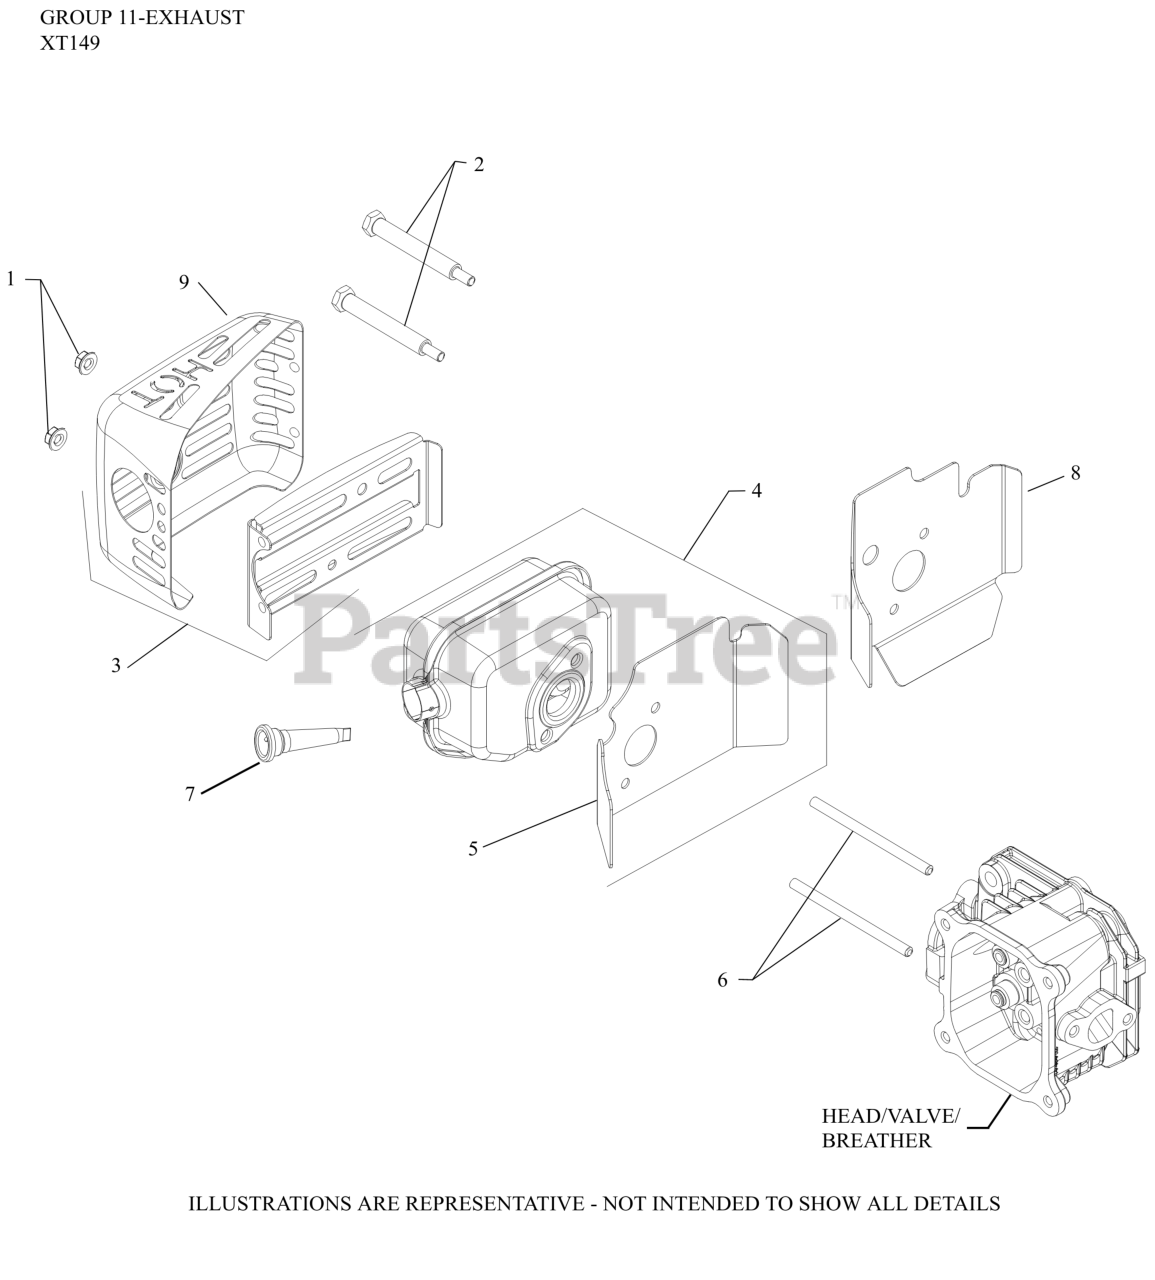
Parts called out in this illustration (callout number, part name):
1	NUT, HEX FLANGE LOCK (M6)
4	KIT, MUFFLER-USE 14 068 15-S
8	GUARD, MUFFLER - DISCONTINUED
9	GASKET, MUFFLER - USE 14 041 22-S
